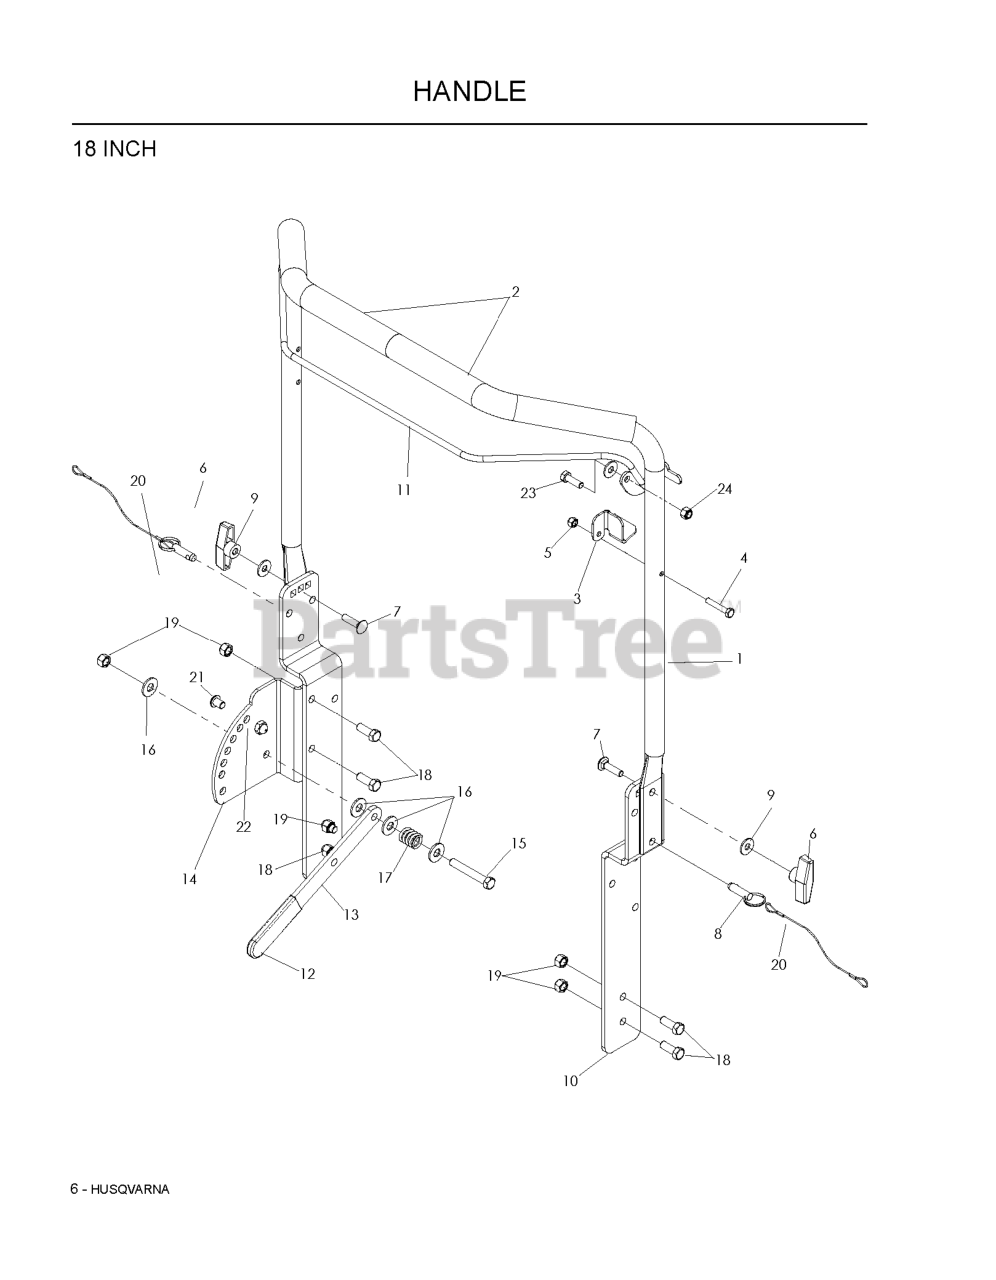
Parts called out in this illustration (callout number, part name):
1	HANDLE GRAY
3	CABLE TAB POWER RAKE
4	SCW 1/4-20 X 1-1/2 HEX
5	NUT.1/4-20.HEX.NYLOC.ZD
7	BOLT, CARRIAGE 5/16X1-1/4
8	DETENT PIN RAKE/DT
9	WASHER 5/16 FLAT
10	HANDLE SIDE GREY
11	BAIL - ORANGE
13	LEVER, PLATED
14	HEIGHT ADJUSTMENT PLATE
15	HCS 3/8C X 2 1/2
16	WASHER 3/8 FLAT
17	COMPRESSION SPRING
18	HCS 3/8-16X1.GRD.5.ZD
19	NUT 3/8-16 NYLOC
21	BLT 3/8-16 X 1/2 BTN HD BLK SP
22	NUT 3/8-16 ACORN HEX
23	HCS 5/16C X 1
24	NUT 5/16 NYLOC
